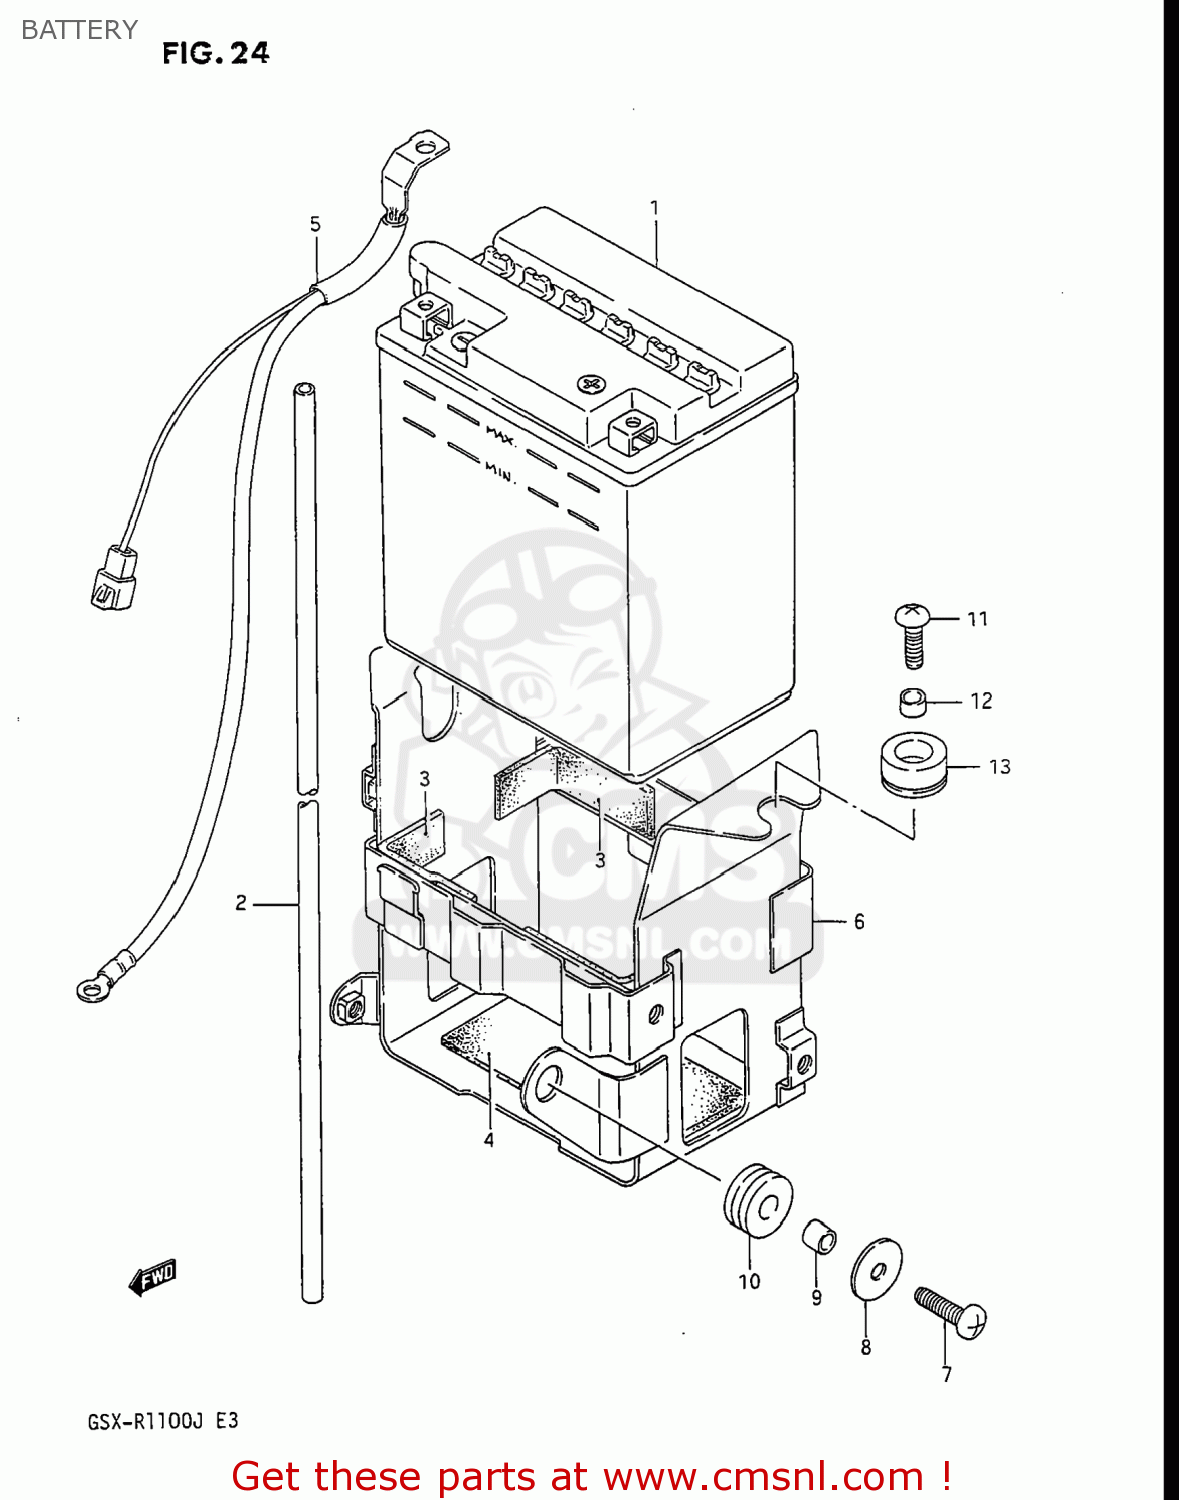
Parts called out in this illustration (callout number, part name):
1	BATTERY ASSY (12V)
2	HOSE,BATTERY EXHAUST
3	PROTECTOR,20X9
4	PROTECTOR(170X95X3.0)
5	WIRE,BATTERY MINUS LEAD
6	HOLDER,BATTERY
7	SCREW
8	WASHER
9	SPACER
10	CUSHION
11	SCREW
12	SPACER
13	CUSHION,HOLDER BATTERY UPR
